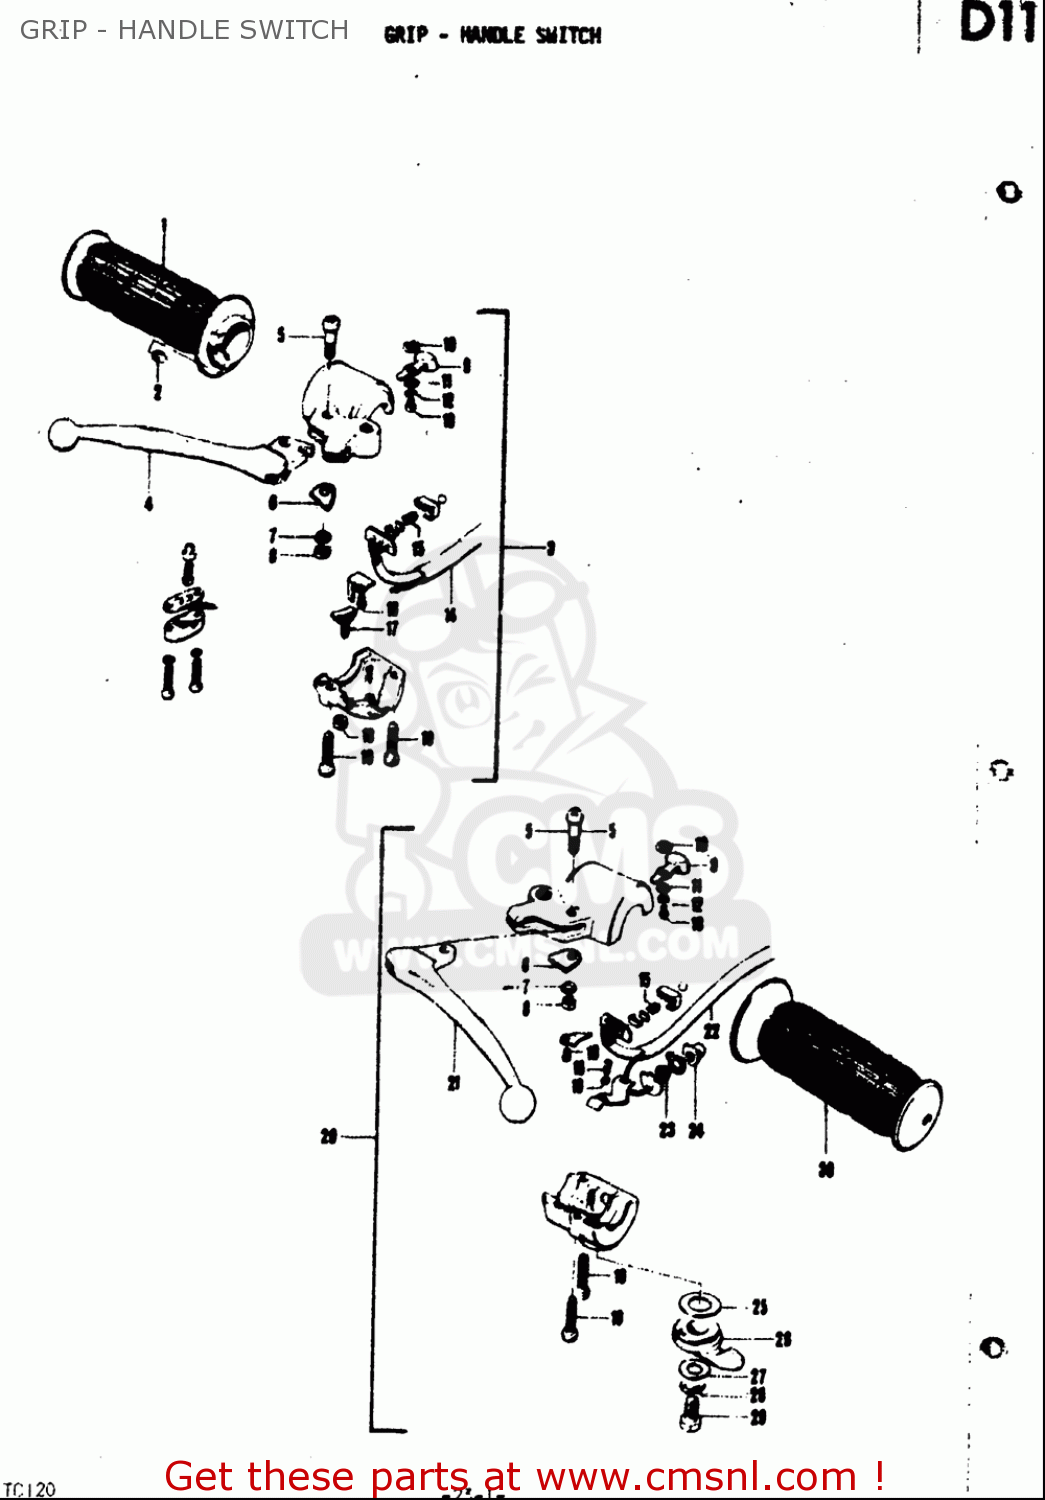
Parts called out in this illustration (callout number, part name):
1	GRIP,THROTTLE
2	PIECE,THROTTLE END
4	LEVER,BRAKE
5	BOLT,LEVER PIVOT
6	SPACER,LEVER
7	WASHER,LOCK
8	NUT
11	WASHER
12	WASHER,LOCK
18	NUT
19	SCREW
21	LEVER,CLUTCH
23	SPRING
24	BUTTON
25	WASHER,ADJUSTER
26	LEVER,STARTER
27	WASHER(6.5X16X1)
28	WASHER,LOCK
30	GRIP
